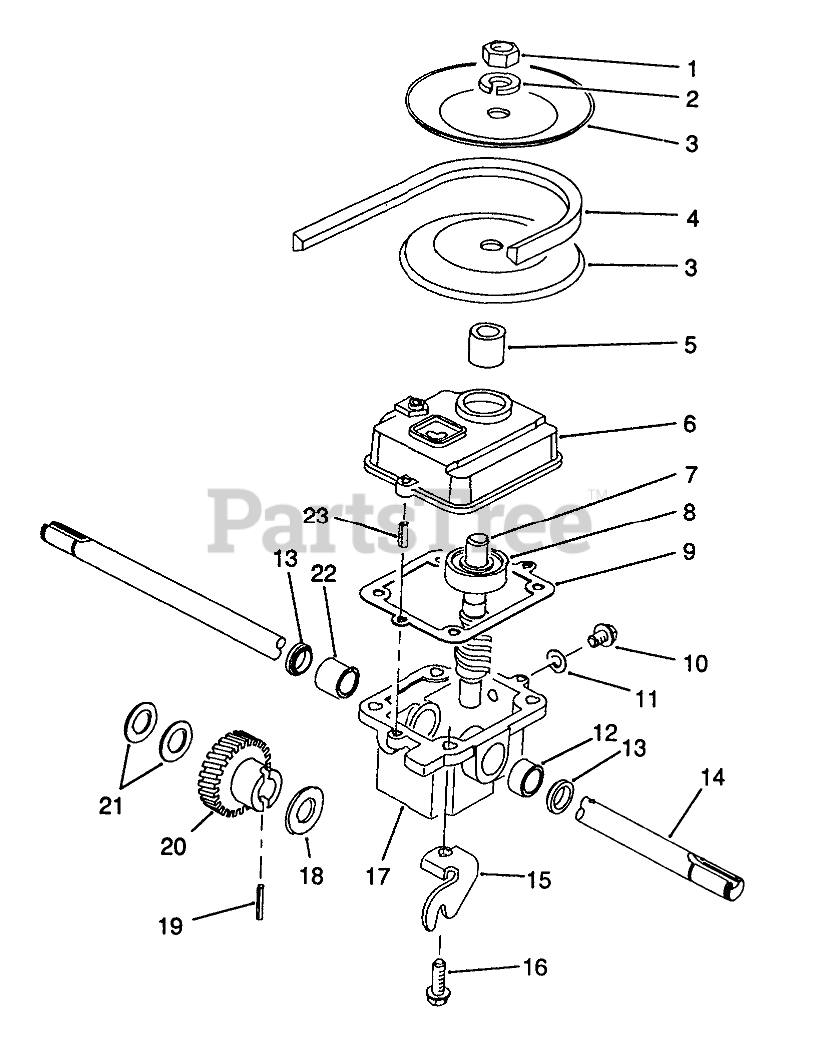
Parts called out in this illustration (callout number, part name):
1	NUT-JAM
2	WASHER-LOCK
3	PULLEY-DRIVEN HALF
4	V-BELT
5	SPACER - PULLEY
6	GEAR CASE COVER
7	SHAFT - WORM
8	BEARING
9	GASKET
10	NYLON SCREW
11	FILL PLUG GASKET
12	BUSHING
13	SEAL-OIL
14	OUTPUT SHAFT
15	TRACTION BRACKET
16	SCREW-HWHTF
17	GEAR CASE
18	THRUST WASHER
19	PIN-SPRING
20	GEAR - HELICAL
21	WASHER-PLAIN
22	BUSHING
23	3/16 X 1/2 ROLL PIN
